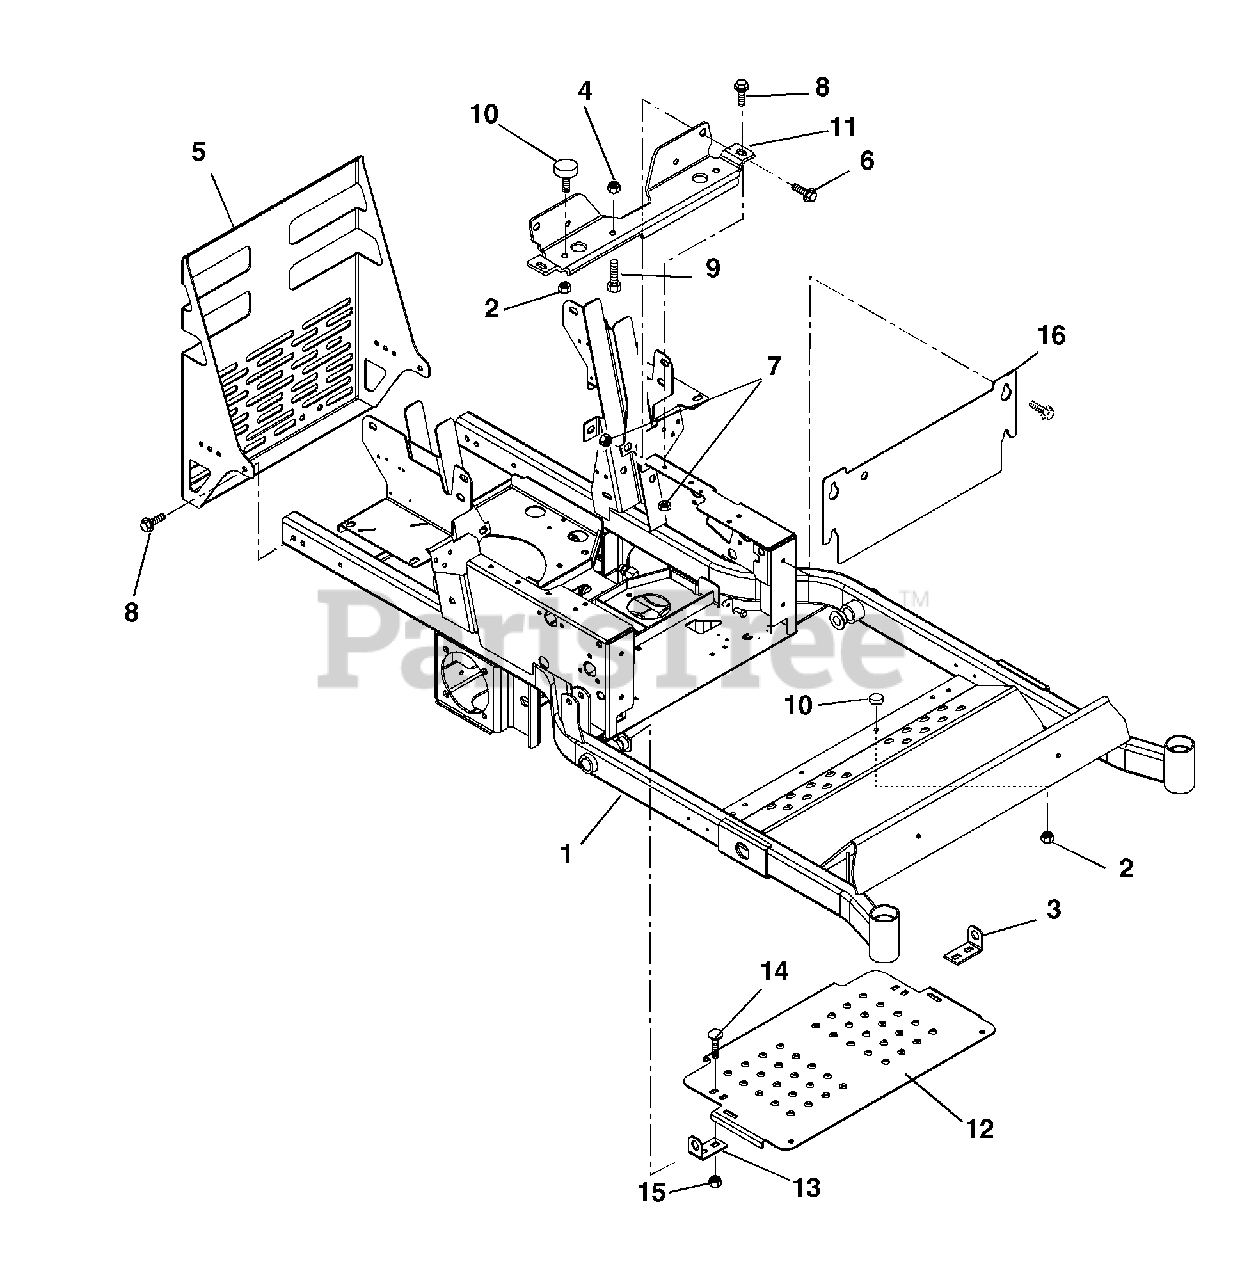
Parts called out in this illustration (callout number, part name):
1	INTERM Z FRAME 44" 48" 52"-BLK
2	@NUT-SPNLK-FLG .312-18 YWZC
3	HINGE, FOOTBOARD LH
4	@NUT-LK-TOP-FLG .31-18 YWZC
5	BUMPER/GUARD - BLACK
6	BLT-SERHFWH .375-16X1.0 YWZC
7	NUT-RTNR .375-16X.37
8	@SCR-TAP .38-16X.50 HWH TR YWZ
9	@BLT-HEX .31-18X1.25 GR5 YWZC
10	BUMPER, RUBBER
11	SEAT SUPPORT - BLACK
12	FOOTREST PANEL - 0RANGE
13	HINGE, FOOTBOARD RH
14	@BLT-RDHDSQNK .38-16X.75 G5YZ
15	@NUT-LK-TOP-FLG .38-16 YWZC
16	ACCESS PANEL - ORANGE
